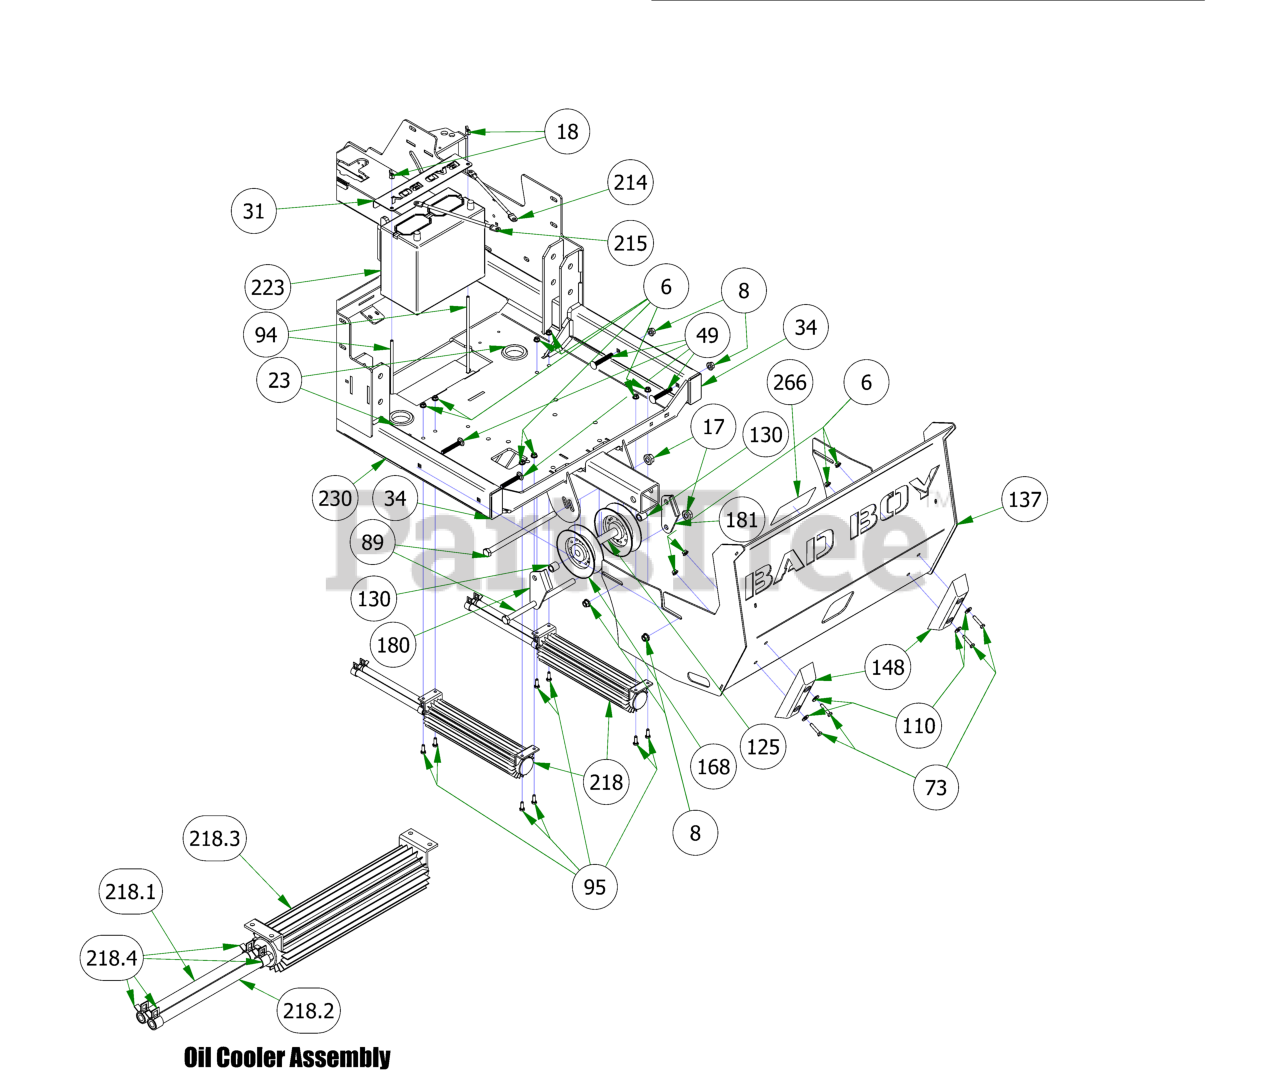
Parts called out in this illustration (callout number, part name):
6	1/4-20 NYL INSERT FLANGE LOCKNUT ZINC
8	3/8-16 NYLON INSERT FLANGE LOCKNUT (GR.F) ZINC
17	1/2-13 NYLON INSERT FLANGE LOCKNUT ZINC
18	1/4-20 WING NUT FORGED (TYPE A) LIGHT SERIES ZINC
23	2019 2" x .25 Rubber Grommet
31	2019 Horizontal Battery Hold Down Cover
34	1 1/2 x 3 Frame Plug
49	3/8" x 2 1/2" Carriage Bolt
73	1/4-20 X 1-1/4 HEX CAP SCREW (GR.5) ZINC
89	1/2-13 X 9 HEX CAP SCREW (GR.5) ZINC
94	1/4-20 X 9 CARRIAGE BOLT ZINC
95	1/4-20 X 3/4 HEX CAP SCREW (GR.5) ZINC
110	1/4 USS FLAT WASHER (3/4 OD) ZINC
125	2019 Pulley Spacer .75 x .5 x 4.375
130	.51 ID X .75 OD X .75 LGTH SOLID SPACER ZINC
137	2019 Horizontal Suspension Rear Cover
148	8" Rubber Bumper
168	2019 Outlaw Horizontal Rear V Pulley
180	Renegade Deck Belt Rear Keeper - Left
181	Renegade Deck Belt Rear Keeper-Right
214	Red Battery Cable - Diesel
215	Black Battery Cable - Diesel
218	Renegade Oil Cooler Assembly
218.1	3/8" Clear Hose
218.2	3/8" Clear Hose
218.3	2019 12" Oil Cooler With Fittings
218.4	3/8" Hose Clamp
223	Battery - Diesel/Renegade Models PF-516
230	2019 Renegade Gas Frame - Powdercoated
266	2019 Renegade Pump Belt Route Decal
